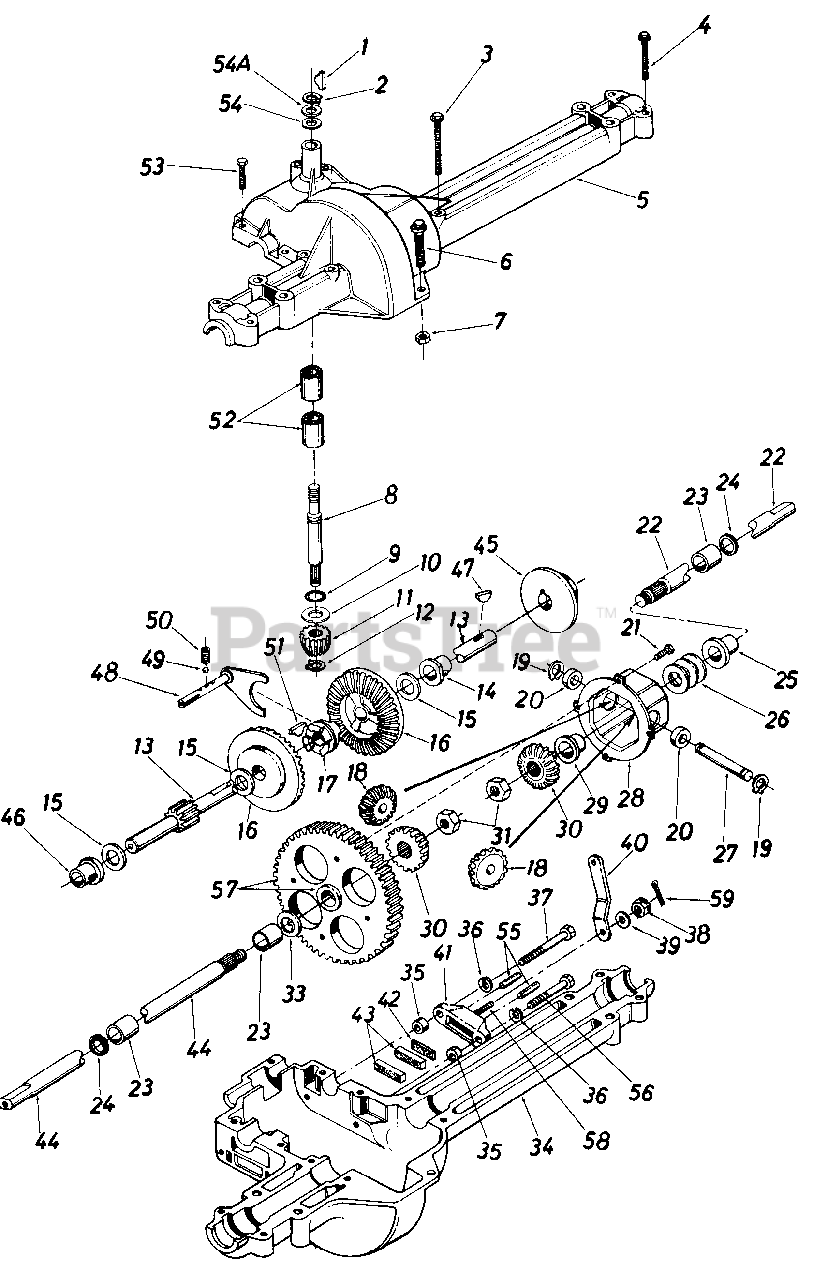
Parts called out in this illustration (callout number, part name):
1	#4 Hi-Pro Key 3/32 x 518" Dia.
2	Snap Ring .625" Shaft
3	Hex Bolt 1/4-20 x 1.75" Lg.*
4	Hex Bolt 1/4-20 x 1.25" Lg.*
5	Upper Housing
6	Hex Fl-Bolt 1/4-20 x .88" Lg.*
7	Hex Nut 1/4-20 Thd.*
8	Input Shaft
9	Square Seal 518" I.D.
10	Thrust Washer 518" I.D. x 1.25" O.D.
11	Pinion Input 14T
12	Retaining Ring 7/16" Ext.
13	Drive Shaft-R.H.
14	Flange Brg. 518" I.D. x 3/4" Lg.*
15	Fl-Wash.
16	Bevel Gear 42T
17	Clutch Collar
18	Miter Gear 15T-H.D.
19	Snap Ring
20	Thrust Bearing 1/2" I.D. x 1.0" O.D.
21	Pan Head Scr. 1/4-20 x .50" Lg. w/Patch
22	Axle R.H.
23	Sleeve Bearing 3/4" I.D. x 1.0" Lg.
24	Oil Seal 3/4" I.D.
25	Flange Bearing 3/4" I.D. x 15/1 6" Lg.
26	Fl-Wash. .760" I.D. x 1.49" O.D.
27	Cross Shaft
28	Differential Housing Ass'y.
30	Miter Gear-H.D.
31	Hex Ins. L-Nut 1/2-20 Thd.
33	Fl-Wash. .760" I.D. x 1.49 O.D.
34	Lower Housing
35	Spacer .53" O.D. x 3/8" Lg.
36	L-Wash. 1/4" I.D.*
37	Hex Bolt 1/4-20 x 1.50" Lg. (Grade 5)
38	Castle Nut 5/16-24 Thd.*
39	Fl-Wash. .344" I.D. x .875" O.D.
40	Actuating Arm-R.H.
41	Brake Yoke
42	Puck Plate
43	Brake Puck
44	Axle L.H.
45	Brake Disc
46	Flange Bearing 5/8" I.D. x 15/16" Lg.
47	Woodruff Key 3/16 x 5/8 HT
48	Shift Fork Ass'y.
49	Ball Detent .250" Dia.
50	Spring Detent
51	#9 Hi-Pro Key 3/16" x 3/4" Dia. HT
52	Needle Brg. 518" I.D. x 1/2" Lg.
53	Hex Bolt 1/4-20 x 1.00" Lg.
54	Fl-Wash. 5/8" I.D. x .030
54A	Fl-Wash. 5/8" I.D. x .040
55	Actuating Pin 5/16" Dia.
56	Hex Bolt 1/4-20 x 1.50" Lg. (Grade 5)
57	Differential Gear 72T Ass'y. w/ Bearing
58	Sq. Hd. Bolt 5/16-24 Thd.
59	Cotter Pin 3132" Dia. x .50" Lg.
